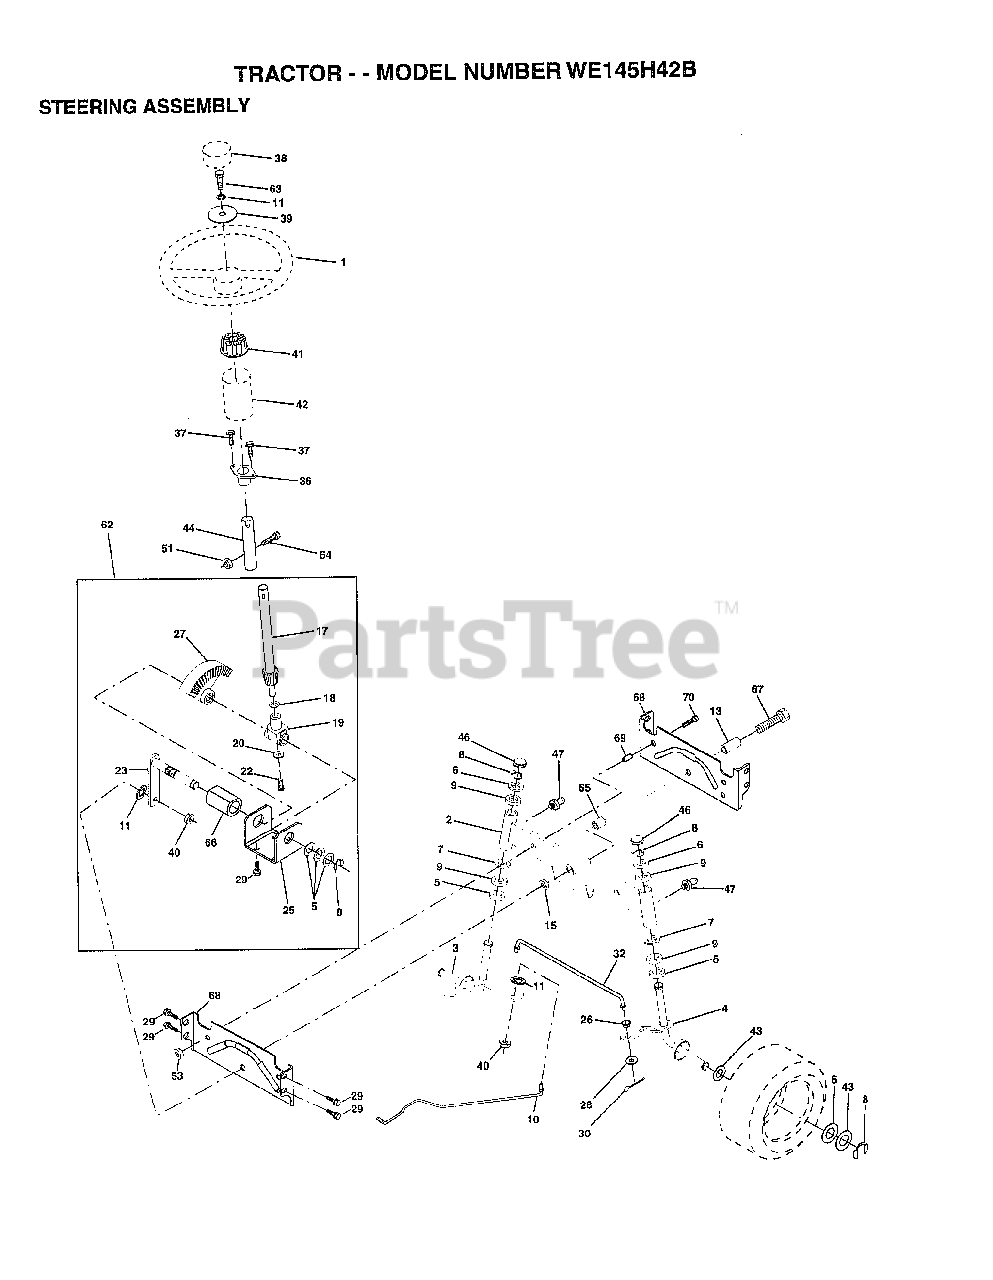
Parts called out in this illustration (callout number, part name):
1	WHEEL STR AYP BLK
2	AXLE ASM
3	SPINDLE.ASM.LH
4	"SPINDLE ASM,RH"
5	WASHER .T
6	WASHER
7	WASHER
8	RING
9	COL. SRTG. BEAR.
10	DRAGLINK-STAMPED
11	LOCKWASHER
13	BEARING AXLE
15	"NUT-LOC,FLANGE LT"
17	SHAFT ASM STEERIN
18	THRUST WASHER
19	SUPPORT.SHAFT
22	SCREW HEX SOC1/4-
25	BRKT-STEERING
26	BUSHING.DRAGLINK
27	GEAR SECTOR
28	WASHER
29	SCREW
30	COTTER PIN
32	TIE ROD
36	BUSHING.STEERING
37	"SCREW-TT,10-32 FL"
38	CAP STEER AYP
39	WASHER T
40	GRIPCO NUT
41	ADAPTER LT
42	BOOT.STEER.PL
43	WASHER
44	EXT SHAFT STEERIN
46	CAP
47	ZERK M
51	NUT
54	BOLT
62	KIT STEERING ASM
63	BOLT
65	SPACER AXLE
66	"BEARING-ARM,PITMA"
67	BOLT
68	BRACE AXLE
69	"SPACER BRCAE,AXLE"
70	BOLT.HEX.3/8-16X2
